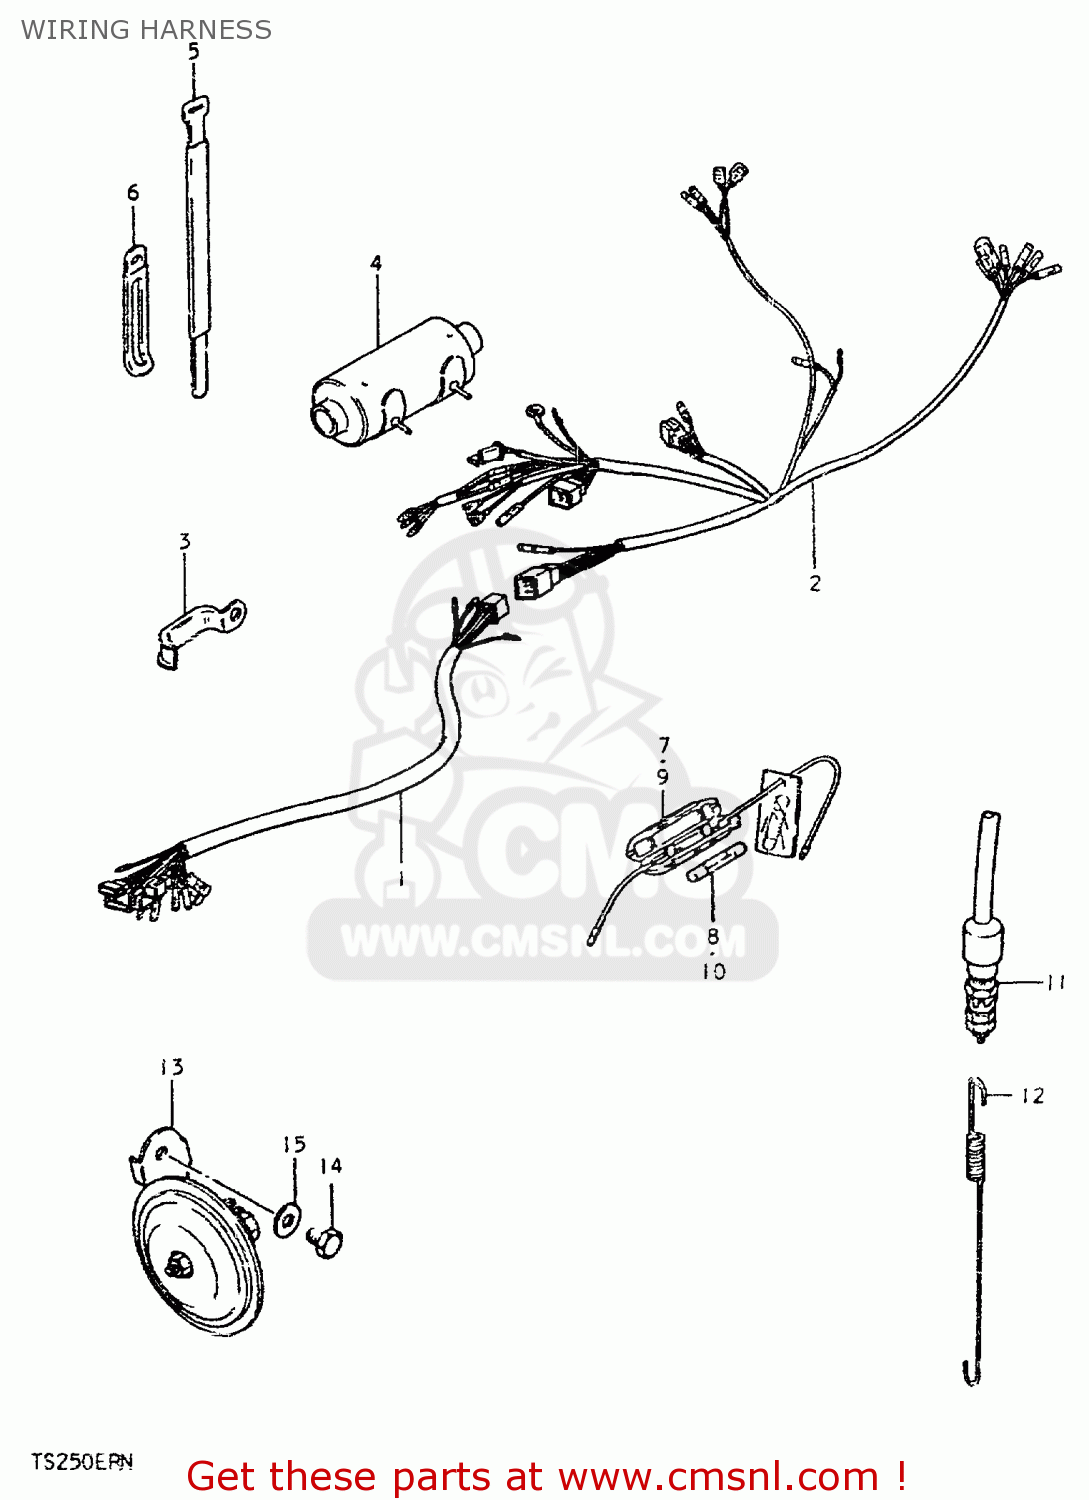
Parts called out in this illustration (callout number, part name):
1	WIRING HARNESS NO.1
2	WIRING HARNESS NO.2
3	CLAMP
4	BOOT,WIRING HARNESS
5	CLAMP
6	CLAMP L:35
7	BOX ASSEMBLY,FUSE
8	FUSE(15A)
11	SWITCH ASSEMBLY,STOP LAMP
12	SPRING
13	HORN ASSEMBLY
14	BOLT
15	WASHER
